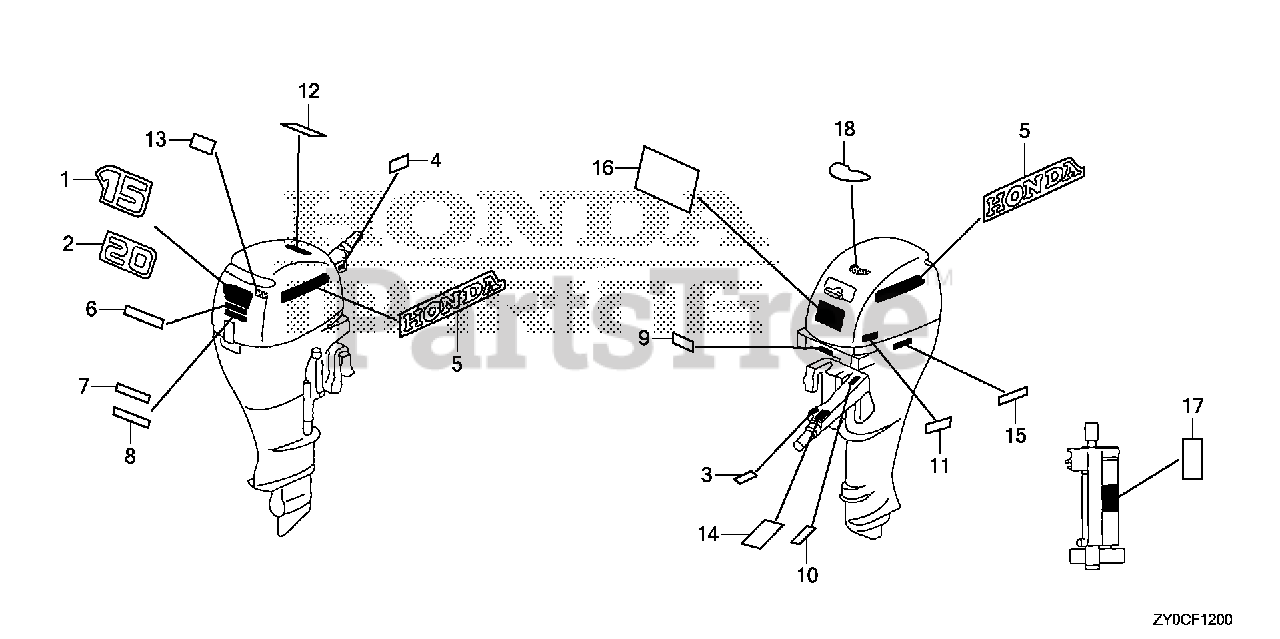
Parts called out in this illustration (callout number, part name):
3	MARK, EMERGENCY SWITCH INDICATION (EU)
4	MARK, STARTER (ENGLISH)
5	MARK, SIDE STRIPE (HONDA)
6	MARK, POWER THRUST
8	MARK, POWER TILT
9	MARK, OIL PRESSURE
10	MARK, CHANGE
13	LABEL, OIL CAUTION (ENGLISH)
14	MARK, THROTTLE (ENGLISH)
15	LABEL, STORING CAUTION (ENGLISH)
16	LABEL, WARNING OPERATOR (ENGLISH)
18	MARK, EMERGENCY STARTER (ENGLISH)
